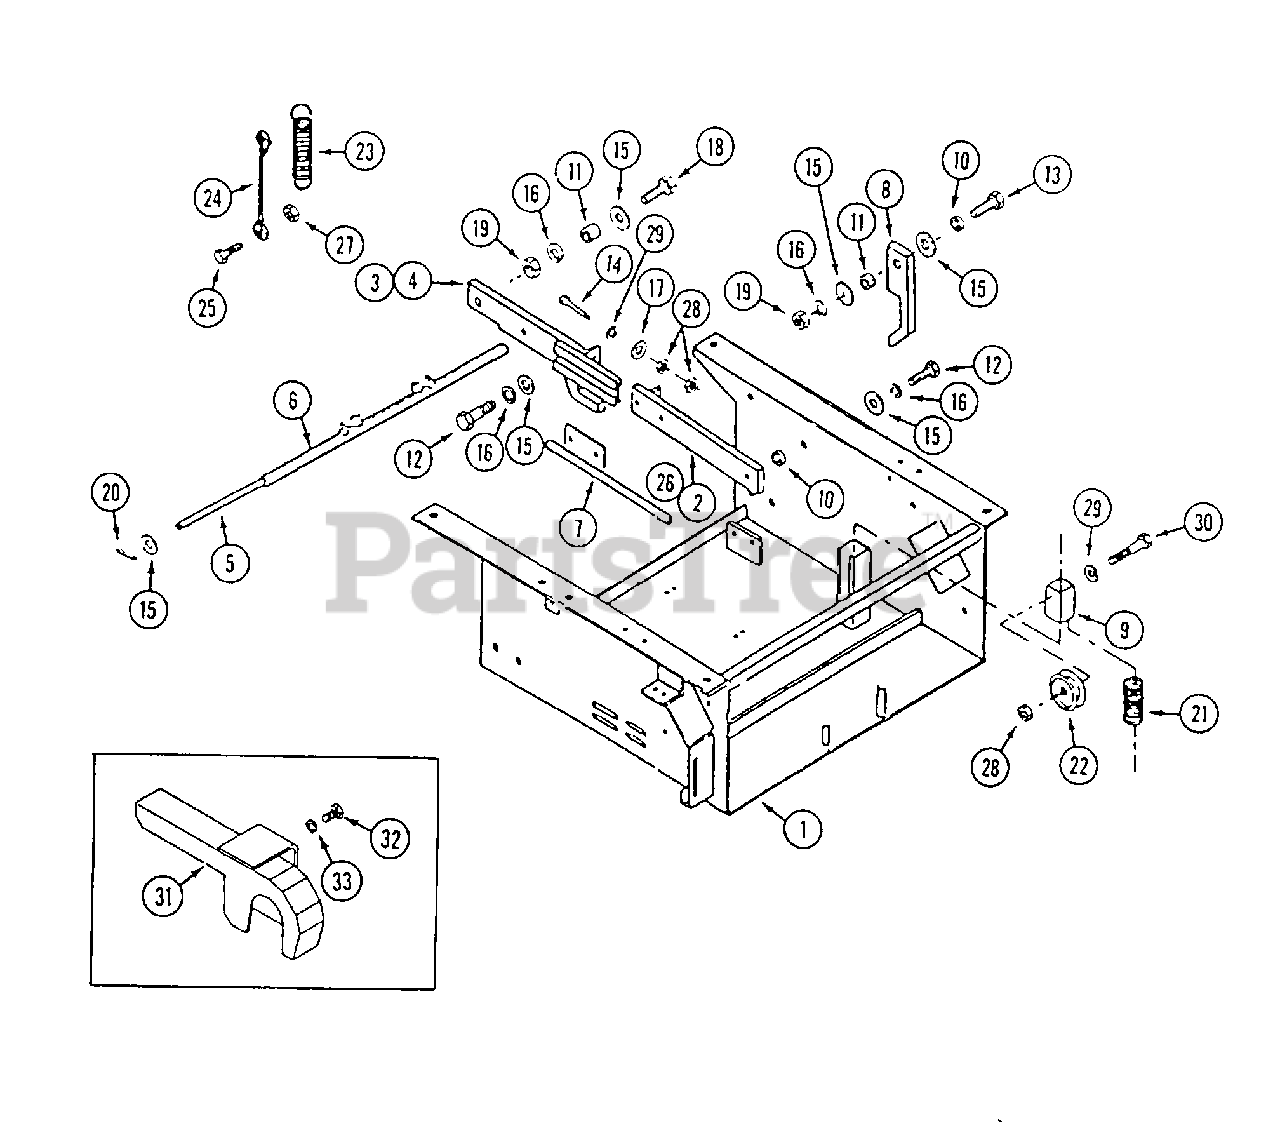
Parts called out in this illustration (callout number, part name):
1	BASE
2	ARM - deck lift R.H.
3	ARM - front L.H.
4	ARM - front R.H.
5	PIN - cross bar
8	LOCK - forward nose down
9	TUBE - drive idler
10	BUSHING - deck lift arm (3/8" long)
11	BUSHING - pivot (1/2" long)
12	BOLT - 1/2" - 13 x 1-1/4"
13	BOLT - 1/2" - 13 x 2-1/4"
14	BOLT - 3/8" - 16 x 3"
15	WASHER - 1/2"
16	LOCKWASHER - 1/2"
17	WASHER - 3/8"
18	BOLT - 1/2" - 13 x 1-1/2"
19	NUT - 1/2" - 13
20	PIN - cotter 1/8" x 1"
21	SPRING - idler tension
22	PULLEY - idler
23	SPRING - lift assist
25	BOLT - 1/4" - 20 x 1"
26	ARM - deck lift L.H.
27	NUT - lock 1/4" - 20
28	NUT - 3/8" - 16
29	LOCKWASHER - 3/8"
30	BOLT - 3/8" - 16 x 2-1/4"
32	BOLT - 5/16" - 18 x 3/4"
33	LOCKWASHER - 5/16"
